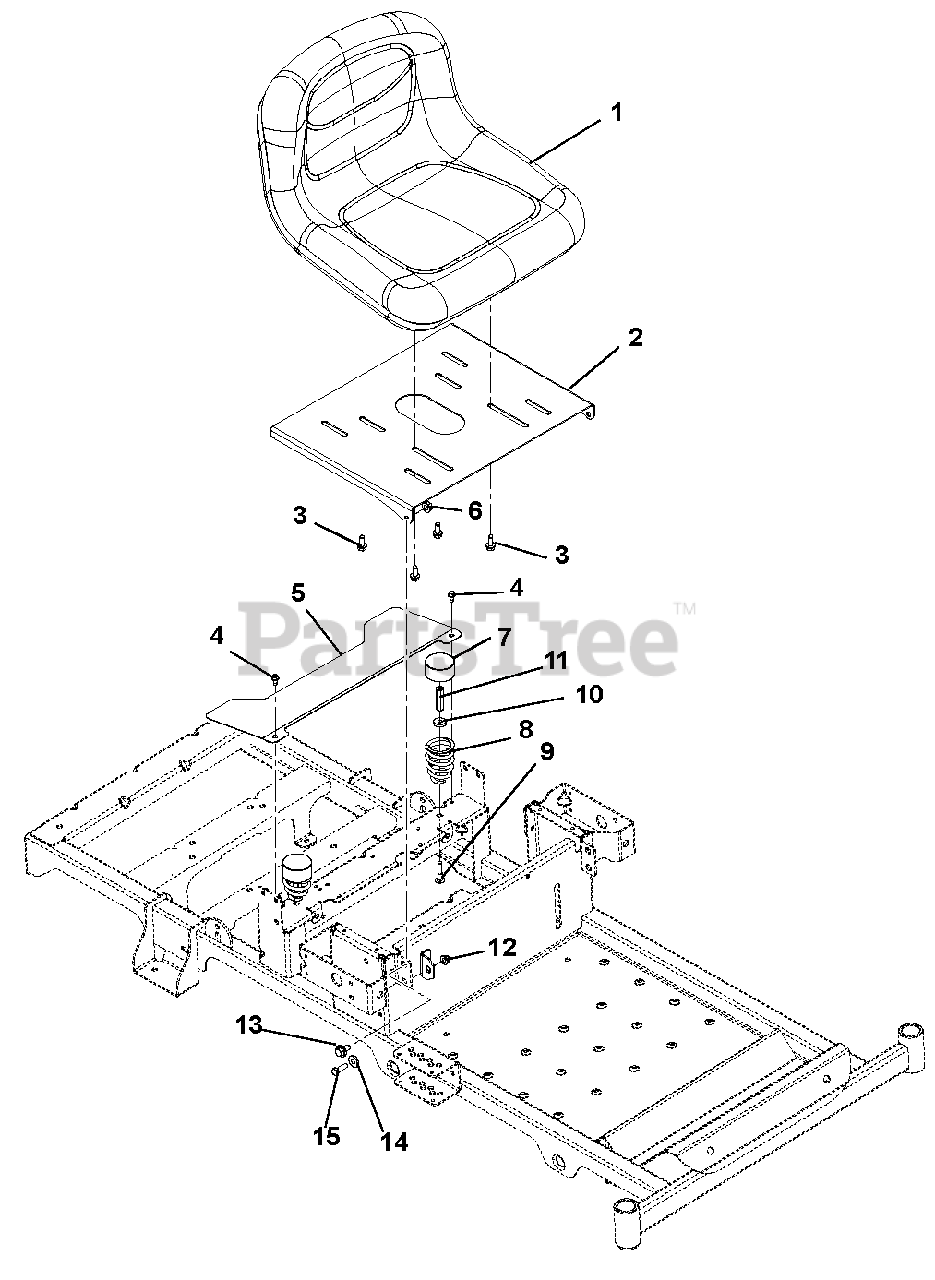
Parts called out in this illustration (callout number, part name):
1	Seat, 13 in Grey (915146, 168)
2	Seat Plate
3	Bolt, Hex 5/16-18 x 3/4
4	Screw, Tapping .25-20 x .50 Hex Washer Head Thread
5	Guard, Fan
6	Nut, .38-16 Locking Top Flange
8	Spring, Seat
9	Bolt, Round Head Square Neck .31-18 x 1.50
10	Washer, Flat, Steel .328 x .87 x .179
11	Nut, Coupling 5/16-18 x 1.75
12	Nut, 5/16-18 Flange Nyloc
13	Bolt, Shoulder .375-16 x .135
14	Bushing, Flange .325 x .499 x .26 x .88
15	Bolt, Hex .31-18 x 1.00
